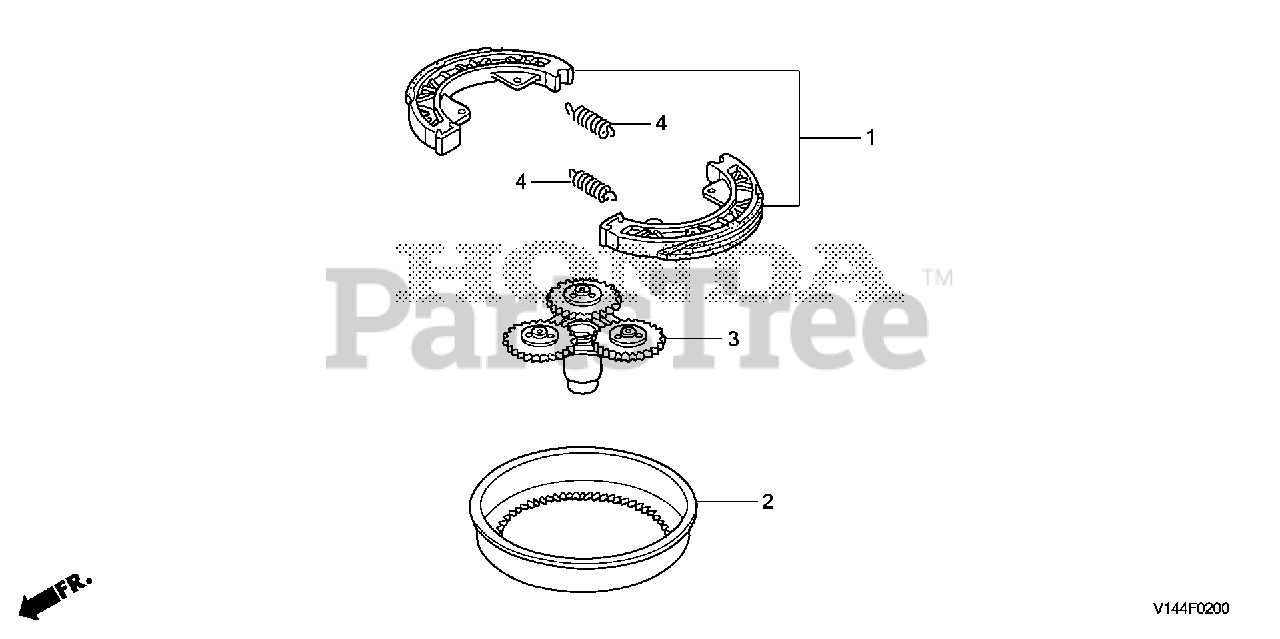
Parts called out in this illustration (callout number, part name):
1	SHOE SET, CLUTCH
2	CLUTCH (OUTER)
3	PLATE, DRIVE
4	SPRING, FR. BRAKE SHOE
